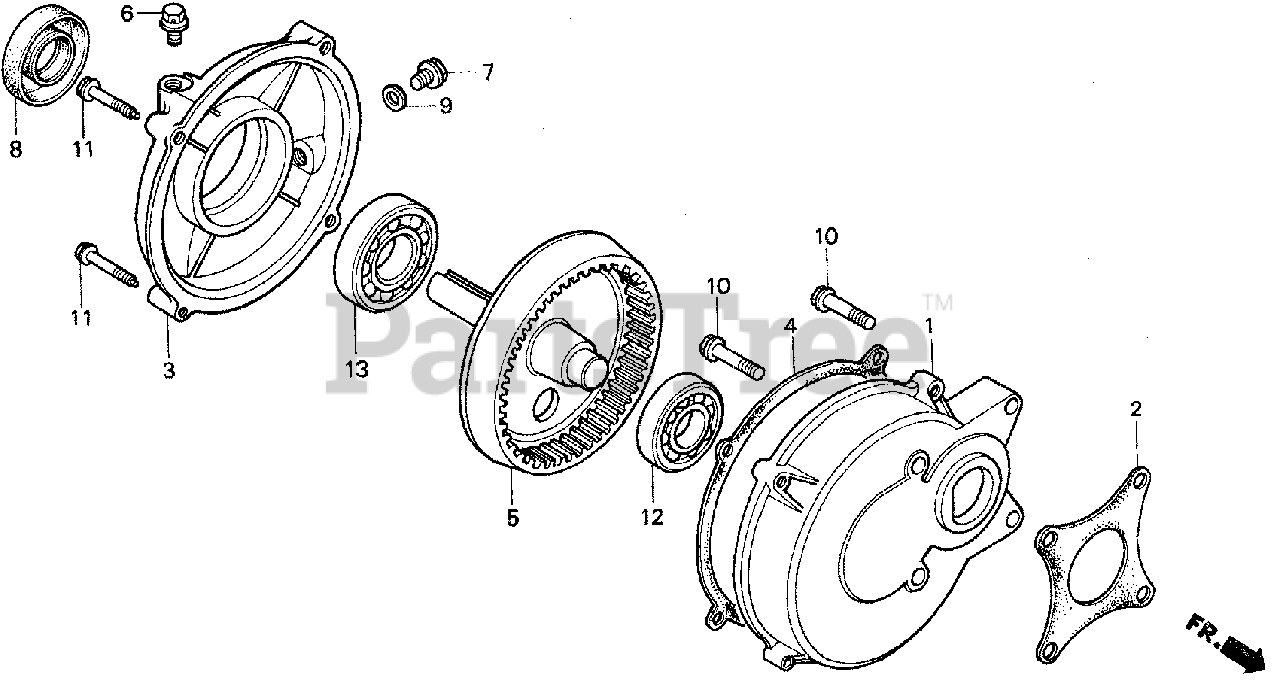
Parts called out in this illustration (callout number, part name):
1	CASE, REDUCTION
2	GASKET, REDUCTION CASE
3	COVER, REDUCTION
4	GASKET, REDUCTION COVER
5	SHAFT, P.T.O.
6	BOLT, BREATHING
7	BOLT, DRAIN PLUG
8	OIL SEAL (25X41X6)
9	WASHER, DRAIN PLUG (12MM)
10	BOLT, FLANGE (8X32)
11	BOLT, FLANGE (8X35)
12	BEARING, RADIAL BALL (6204)
13	BEARING, RADIAL BALL (6305)
